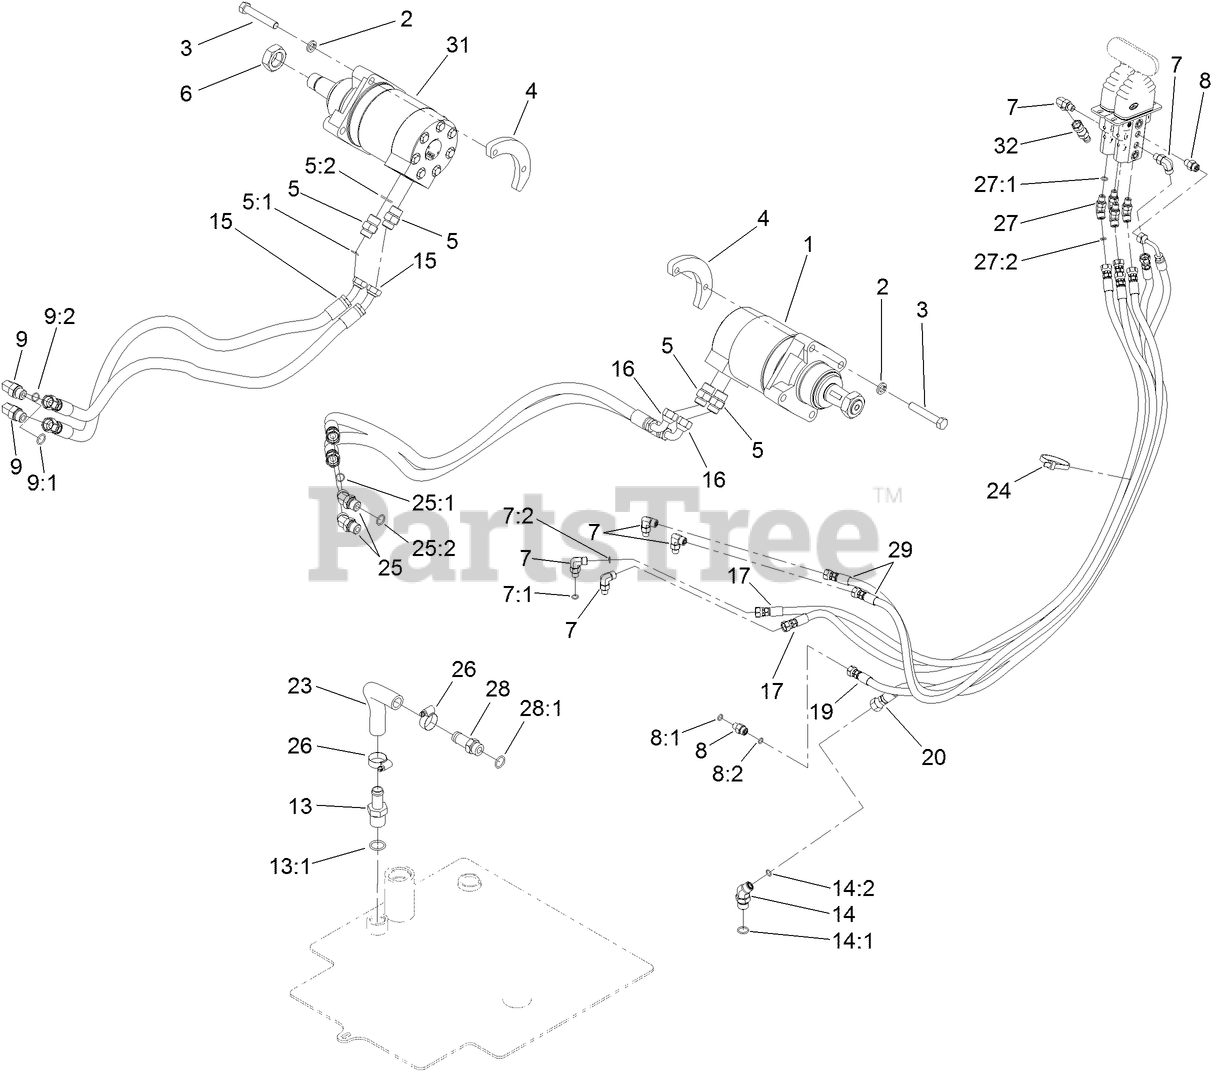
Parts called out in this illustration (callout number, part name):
1	MOTOR-HYD
2	WASHER-LOCK
3	SCREW-HH, TAP
4	PLATE-MOUNTING, WHEELMOTOR
5	FITTING-STRAIGHT
5:1	O-RING
5:2	O-RING
6	NUT-HEX
7	FITTING-ELBOW, 90 DEG
7:1	O-RING
7:2	O-RING
8	FITTING-STRAIGHT
8:1	O-RING
8:2	O-RING
9	FITTING-ELBOW, 90 DEG
9:1	O-RING
9:2	O-RING
13	FITTING
13:1	O-RING
14	FITTING-HYD, 45 DEG
14:1	O-RING
14:2	O-RING
15	HOSE-HYD
16	HOSE-HYD
17	HYD HOSE ASM
19	HYD HOSE ASM
20	HYD HOSE ASM
23	HOSE-RETURN
24	TIE-CABLE
25	FITTING-HYD, 45 DEG
25:1	O-RING
25:2	O-RING
26	CLAMP-HOSE
27	FITTING-HYD, 45 DEG
27:1	O-RING
27:2	O-RING
28	FITTING-STR
28:1	O-RING
29	HYD HOSE ASM
31	MOTOR-HYD
32	NIPPLE-TEST
